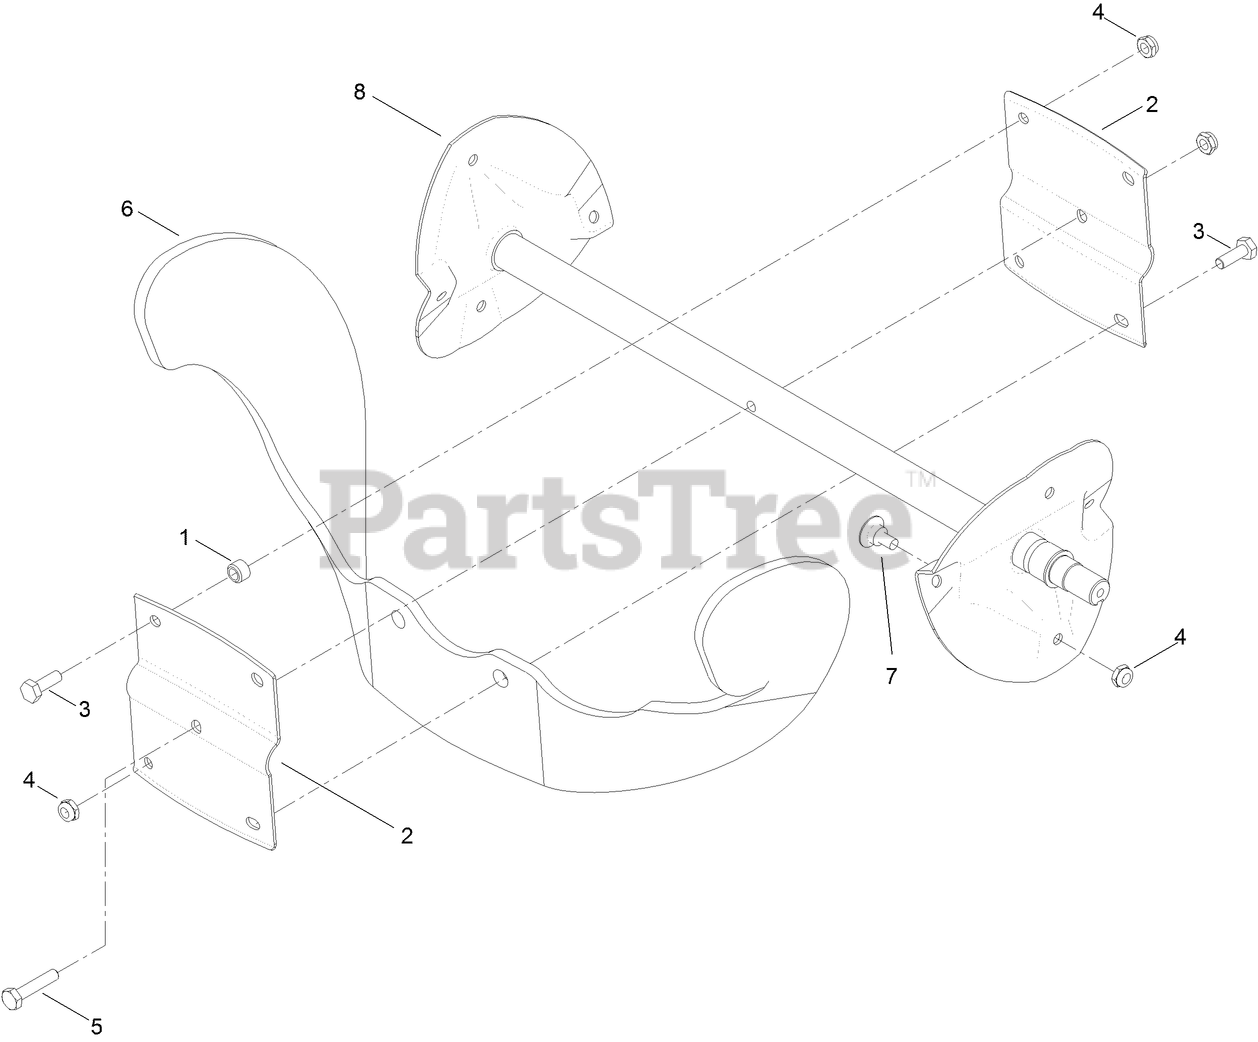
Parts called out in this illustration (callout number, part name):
1	SPACER-BLADE, ROTOR
2	HALF-ROTOR
3	SCREW-HH
4	NUT-LOCK, NI
5	SCREW-HH
6	BLADE-ROTOR
